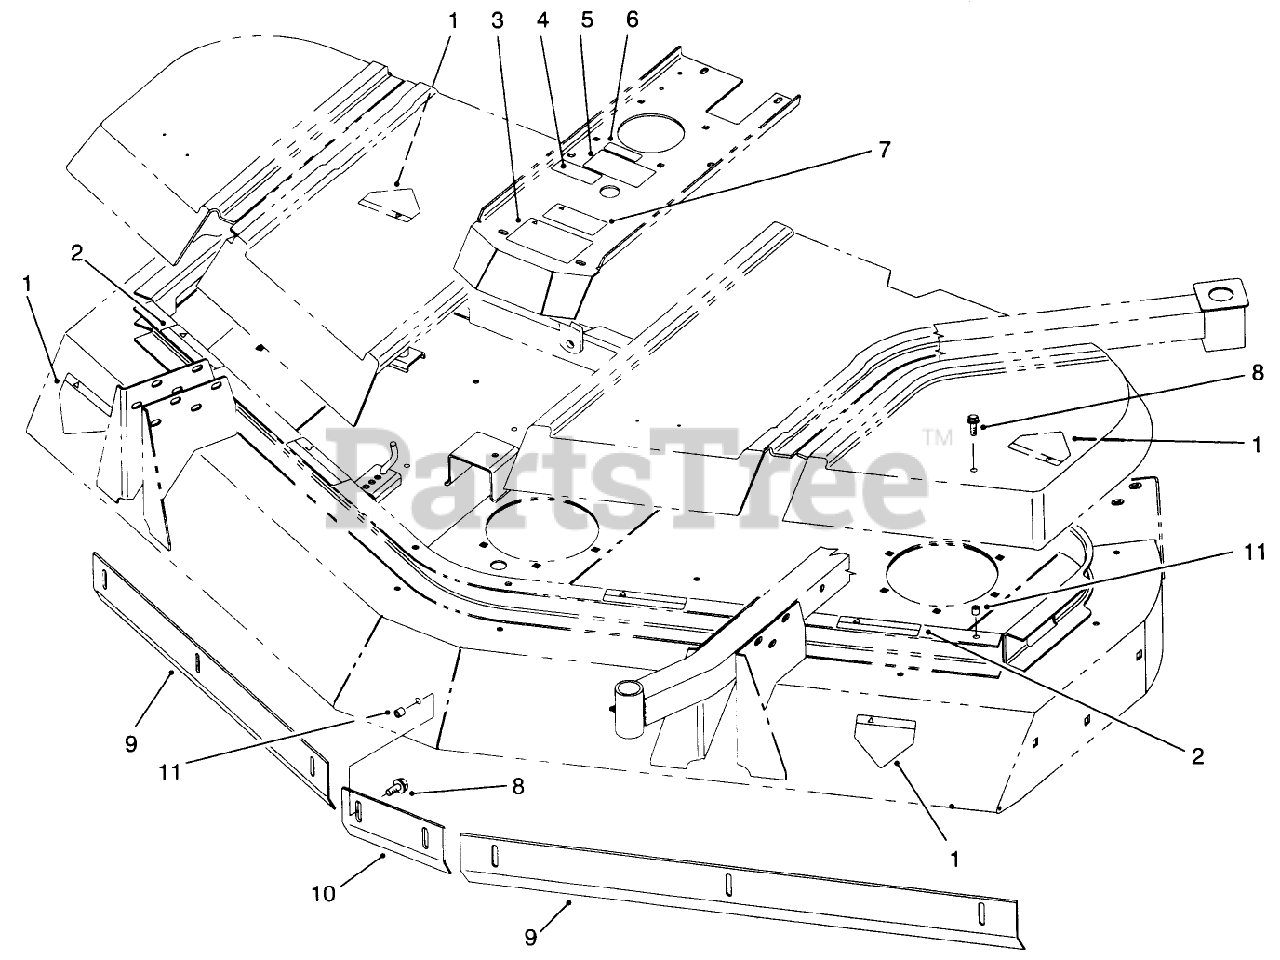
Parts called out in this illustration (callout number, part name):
1	DECAL-DANGER, INT'L
2	DECAL-DANGER
3	DECAL-WARNING
4	DECAL BLANK
5	DECAL-HEIGHT OF CUT
6	DECAL-LUBE
7	DECAL-TORQUE, BLADE BOLT
8	SCREW-HHF
9	Baffle-Side
10	Baffle-Center
11	NUT-INSERT
